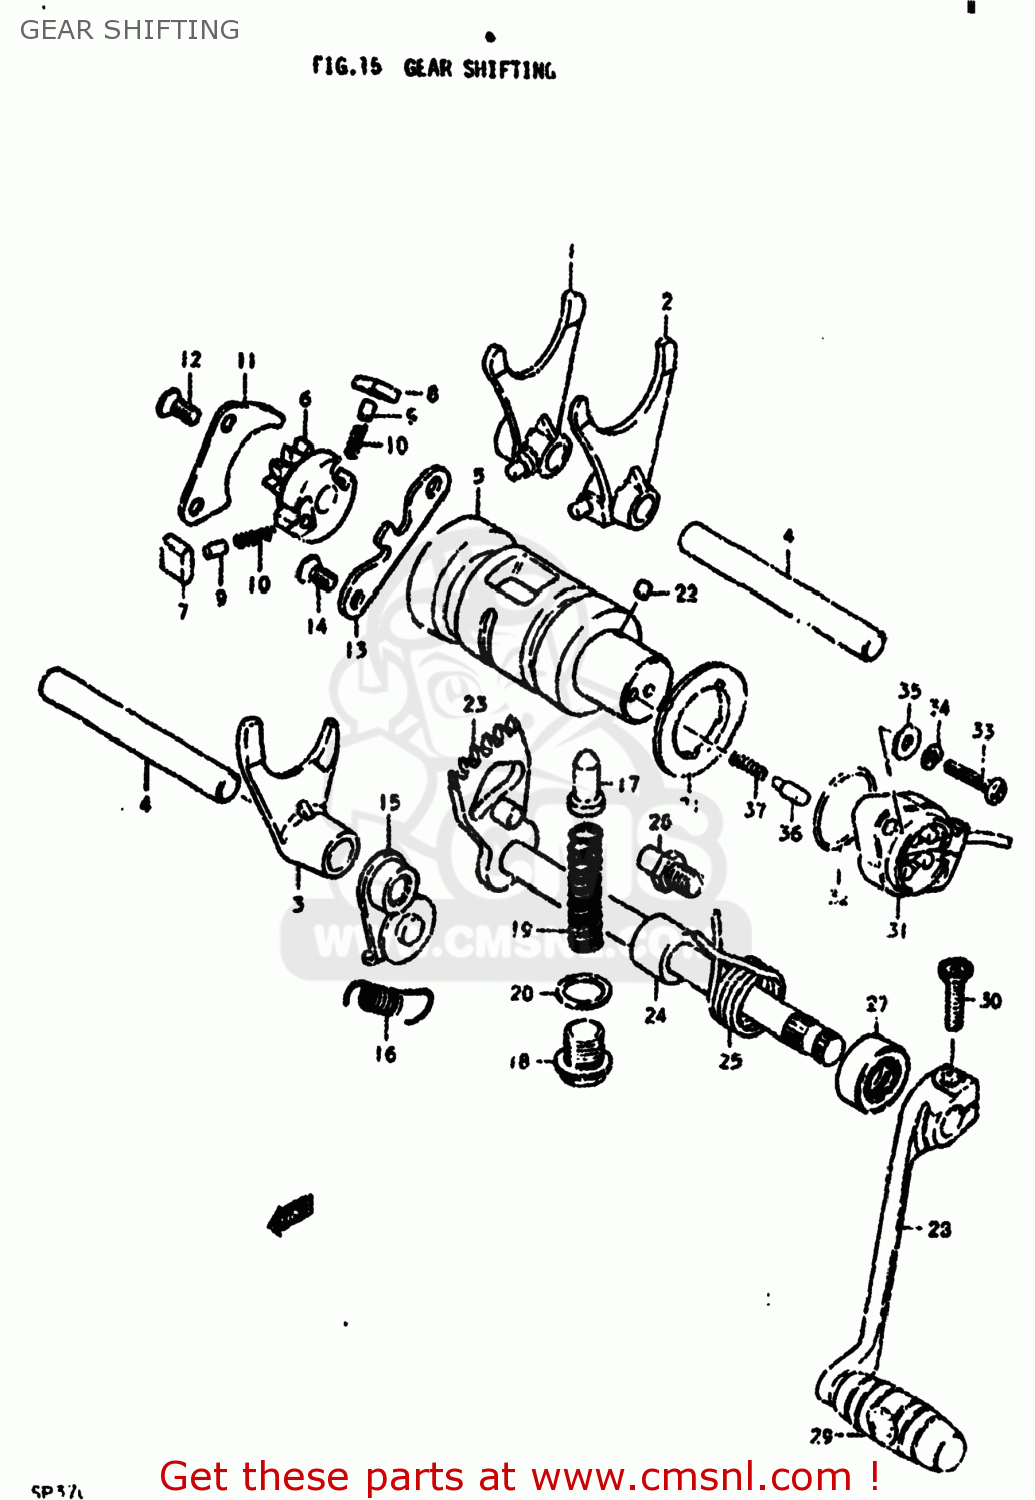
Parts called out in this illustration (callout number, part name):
1	FORK,GEAR SHIFT NO.1
2	FORK,GEAR SHIFT NO.2
3	FORK,GEAR SHIFT NO.3
4	SHAFT,GEAR SHIFT FORK
5	CAM,GEAR SHIFT
6	RETAINER,GEAR SHIFT CAM
7	PAWL,GEAR SHIFT NO.1
8	PAWL,GEAR SHIFT NO.2
9	PIN(5X8)
10	SPRING
11	LIFTER,GEAR SHIFT PAWL
12	SCREW
13	GUIDE,GEAR SHIFT CAM
14	SCREW
15	STOPPER,GEAR SHIFT CAM
16	SPRING
17	STOPPER,GEAR SHIFT CAM NO.2
18	PLUG
19	SPRING
20	GASKET(14X19.2X2) (NAS)
21	PLATE,GEAR SHIFT CAM STOPPER
22	PIN 4X6
23	SHAFT,GEAR SHIFT
24	SPACER(12X20X15.3)
25	SPRING
26	STOPPER,GEAR SHIFT CAM
27	OIL SEAL
28	LEVER ASSEMBLY,GEAR SHIFTING
29	RUBBER,GEAR SHIFT PEDAL
30	BOLT
31	TERMINAL BASE,NEUTRAL SWITCH
32	O-RING (D:2.4 ID:26.2)
33	SCREW 5X20
34	LOCK WASHER
35	WASHER
36	PIN(5X15.5)
37	SPRING
